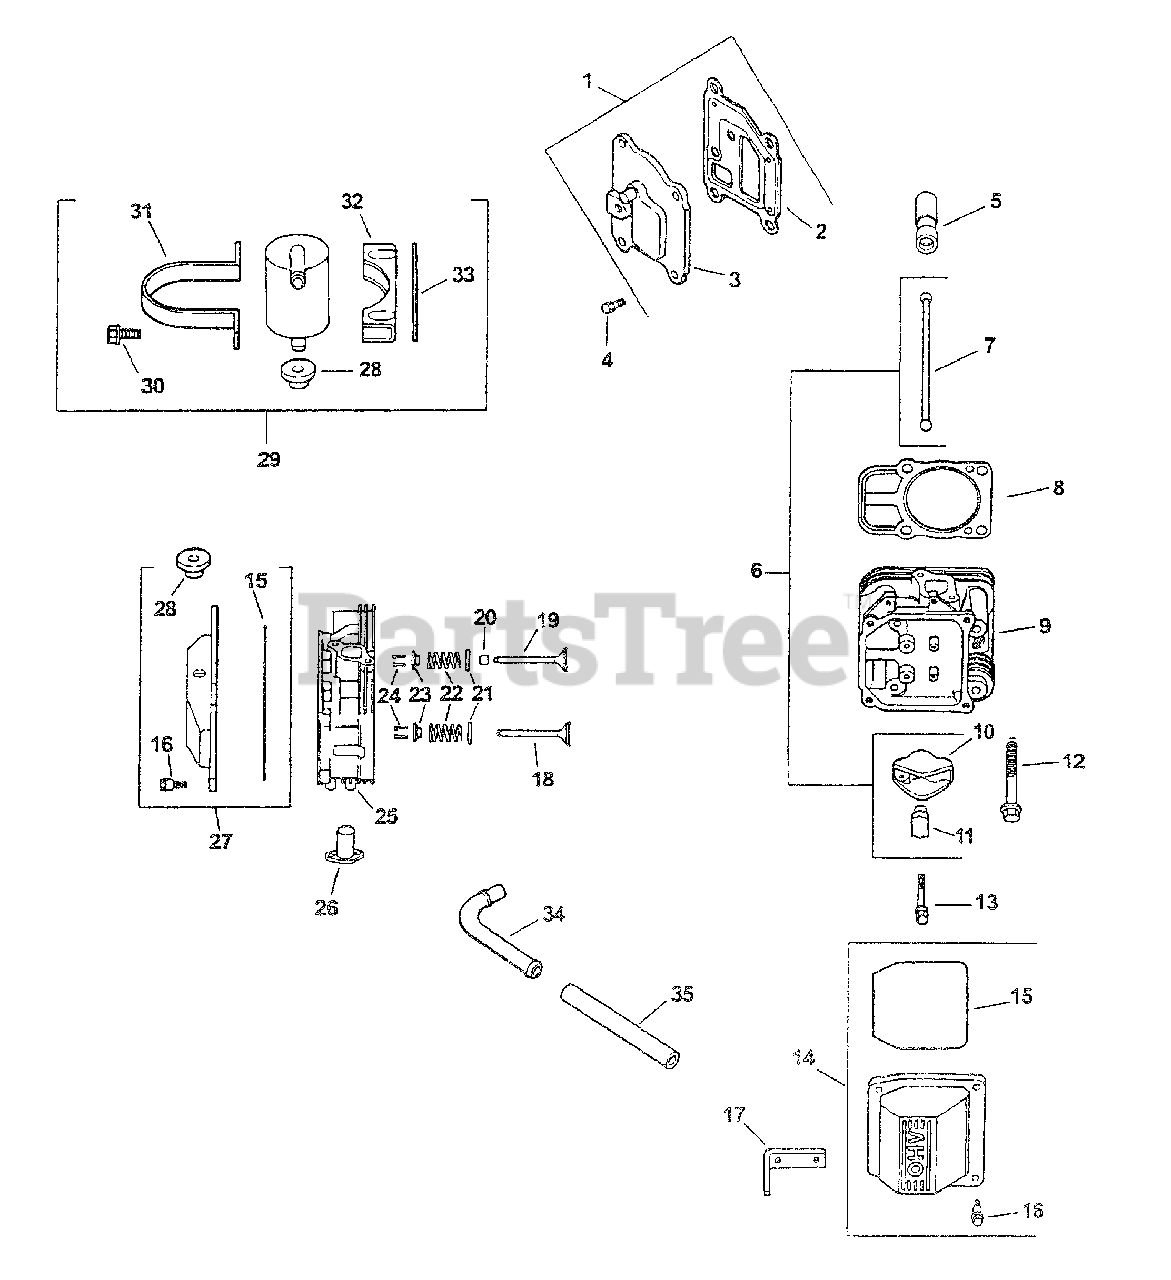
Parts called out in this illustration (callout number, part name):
1	Kit, Breather Cover w/Gaskets
2	Gasket, Breather
3	Cover, Breather
4	Screw, Hex Flange
5	Lifter, Valve
6	Kit, Valve Train
8	Gasket, Cylinder Head
9	Head Assembly, #2 Cylinder
11	Pivot, Rocker Arm
12	Screw, Hex Flange
13	Screw, Hex Flange
14	Kit, Valve Cover - Plain
15	O-Ring
16	Screw, Shoulder
17	Strap, Lifting
18	Valve, Exhaust
19	Valve, Intake
20	Seal, Valve Stem
21	Retainer, Spring
22	Spring, Valve
23	Cap, Valve Spring
24	Kit, Retainer
25	Head Assembly, #1 Cylinder
26	Liner, Exhaust Port
27	Kit, Valve Cover - Breather
28	Grommet, Rubber
29	Kit, Breather Separator
30	Screw, Hex Flange
31	Strap, Breather
32	Bracket, Breather Separator
35	Hose, Flexible
